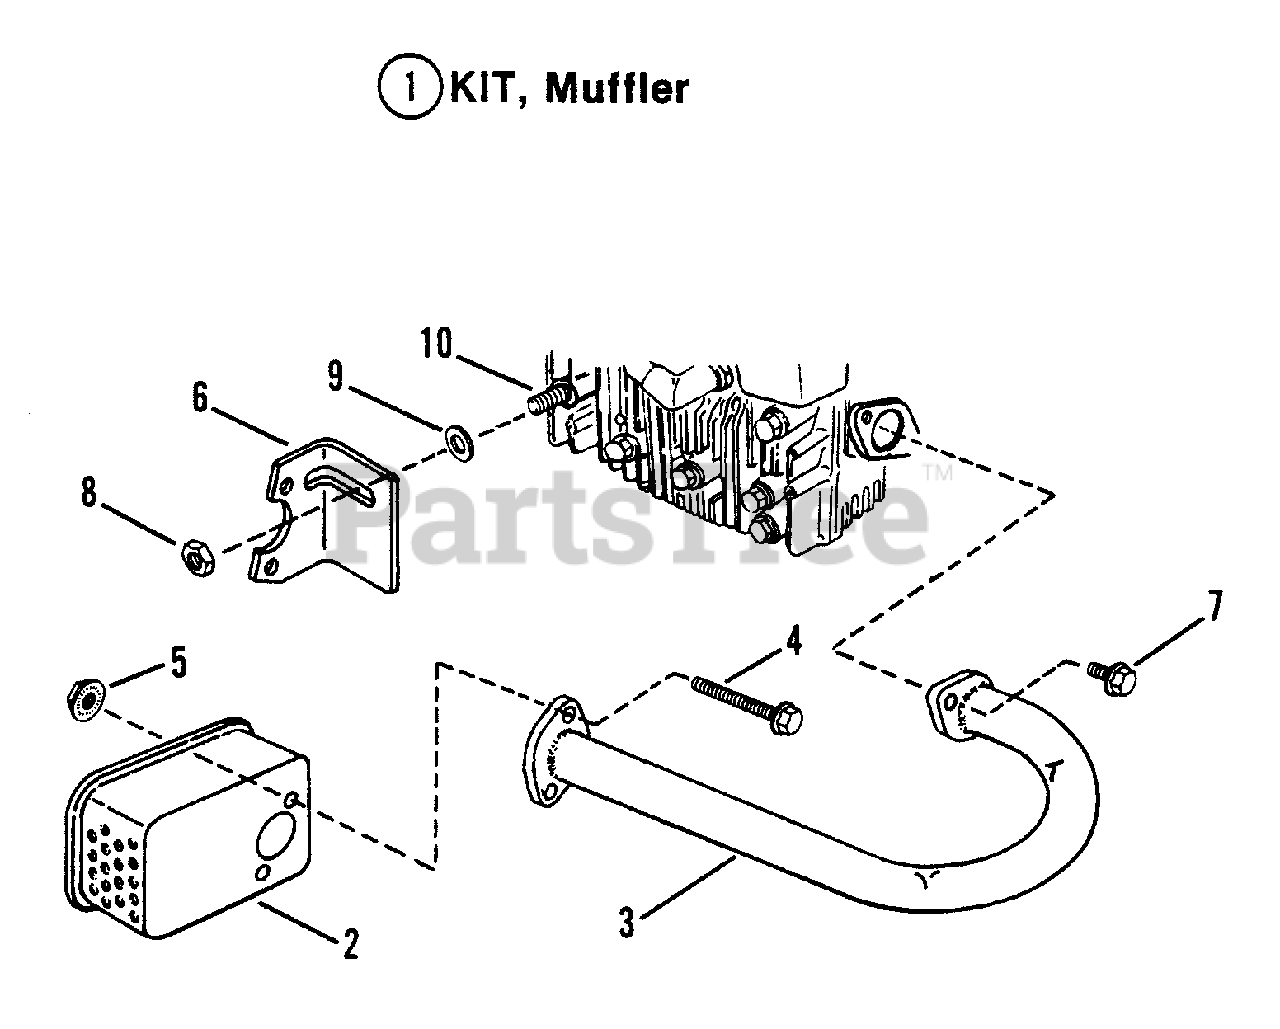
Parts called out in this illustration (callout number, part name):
1	KIT, Muffler
2	MUFFLER
3	TUBE, Exhaust
4	SCREW, 5/16-18 x 3" Hex Head Cap
5	NUT, 5/16-18 Hex Flange Lock
6	BRACKET, Muffler
7	SCREW, 1/4-20 x 5/8" Hex Head Cap
8	NUT, 5/16-18 Hex
9	WASHER, 21/64 Flat
10	STUD, Cylinder Head
